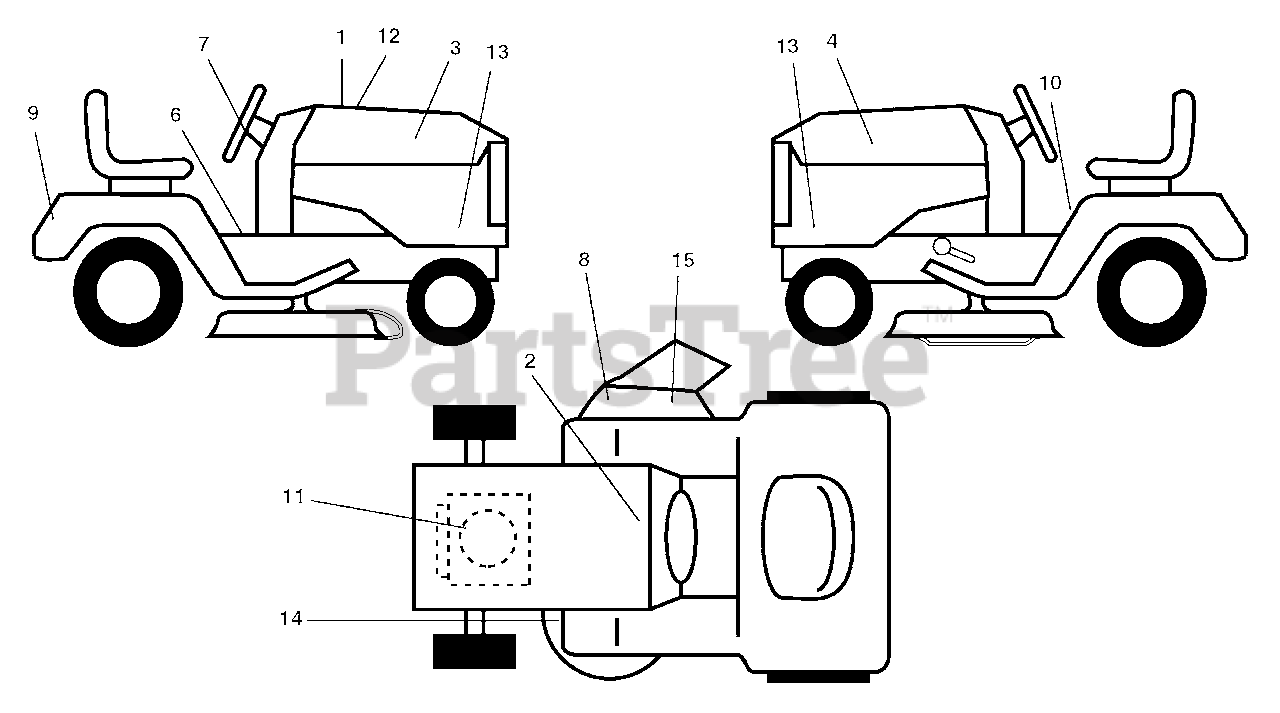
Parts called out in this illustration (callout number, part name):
1	Decal Hood Cust. Resp.
2	Decal Battery
3	Decal Hood RH
4	Decal Hood LH
6	Decal Fender Oper
7	Decal Wheel Steering
8	Decal Warning Keep Hand Away
9	Decal Fender Husq
10	Decal Fender Danger E/F
11	Decal Engine
12	Decal Hood Replacement
13	Decal Hoodsides
14	Decal V-Belt Schematic
15	Decal Deck B 42
